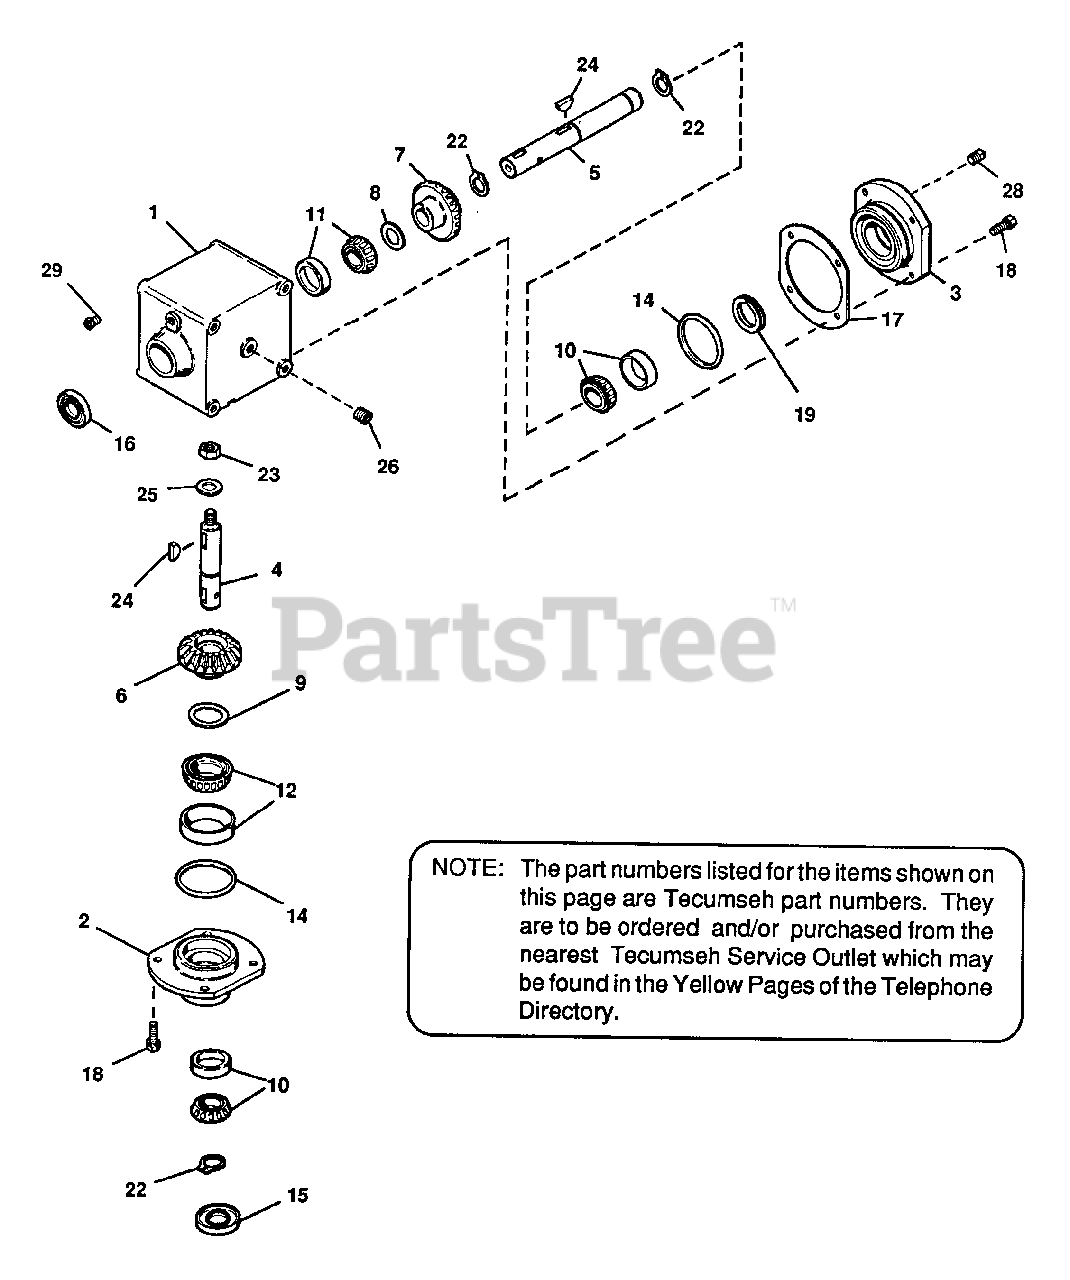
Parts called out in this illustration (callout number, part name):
1	Housing, Right Angle Drive
2	Cap, Retainer
3	Cap, Retainer
4	Shaft, Input (5.38" long)
5	Shaft, Output (7.656" long)
6	Gear, Bevel(25 teeth)
7	Gear, Bevel(26 teeth)
8	Shim (1-1/2" O.D. x 1-1/64" I.D. x .002 thick)
9	Shim (2.000" O.D. x 1.531" I.D. x .002 thick)
10	Bearing & Cup Assy.
11	Bearing & Cup Assy.
12	Bearing & Cup Assy.
14	"O" Ring
15	Seal, Oil
16	Seal, Oil
17	Shim,Cap Retainer
18	Screw, Hex Head, Sems, 5/16-18 x 1
19	Ring, Load
22	Ring, Retaining
23	Jam Nut, 3/4-16
24	Key, Woodruff
25	Washer, Flat
26	Plug, Pipe 1/4-18
28	Plug, Pipe 1/8-27
29	Valve, Relief
